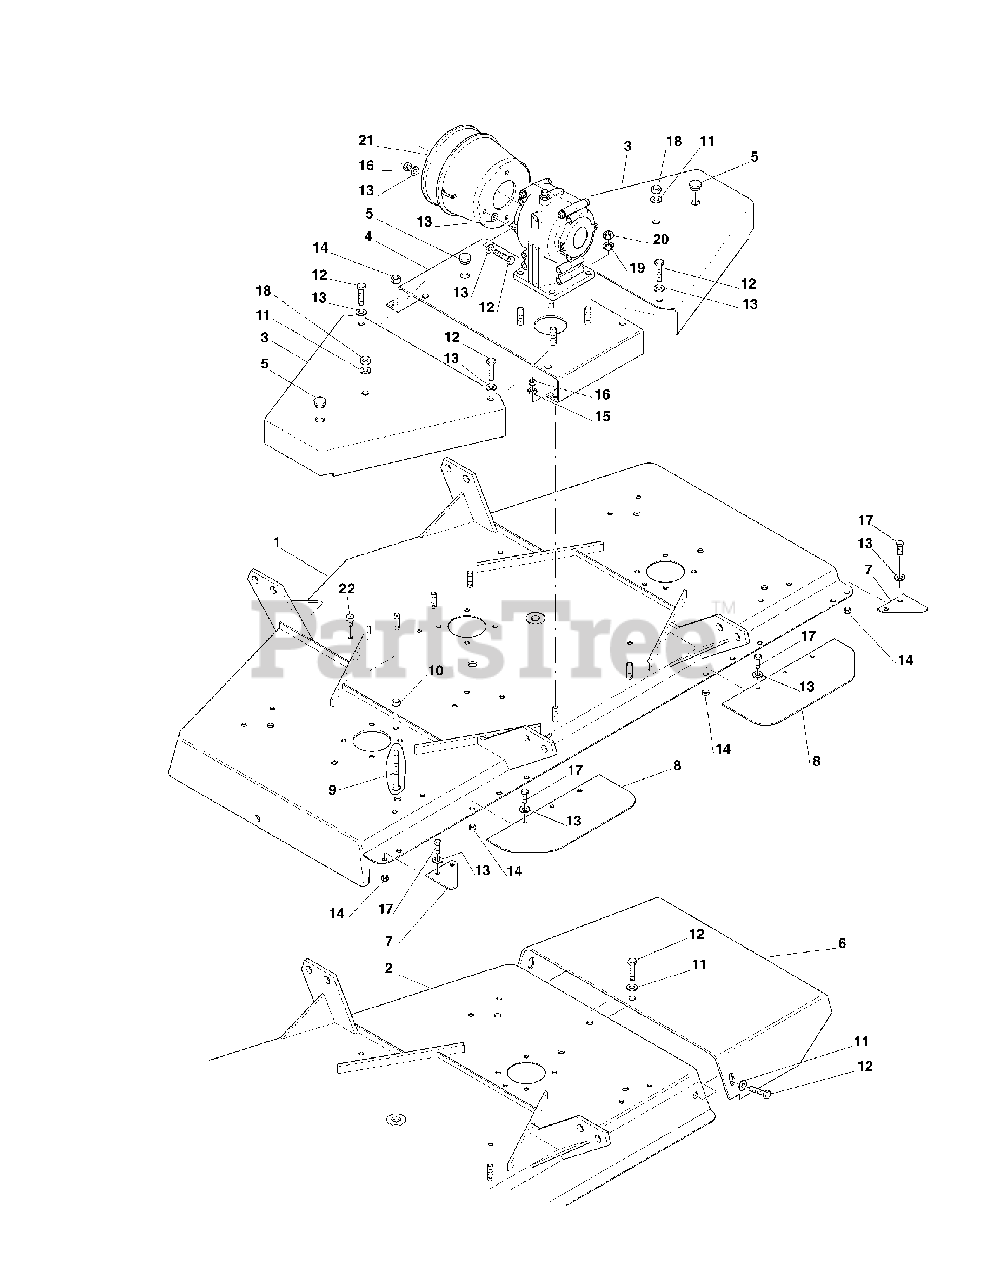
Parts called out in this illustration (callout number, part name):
1	Frame 48'' Rear Discharge
1	Frame 60'' Rear Discharge
1	Frame 72'' Rear Discharge
3	Belt Shield 48''
3	Belt Shield 60''
3	Belt Shield 72''
4	Central Plate 48''
4	Central Plate 60''
4	Central Plate 72''
5	Cap
6	Deflector 60''
7	Side Rear Protection 60''
7	Side Rear Protection 72''
8	Central Rear Protection
9	Bolt TE 10 x 110
10	Nut D. 10
11	Flat Washer D. 10
12	Bolt TE 10 x 110
13	Flat Washer D. 10
14	Nut D. 10
15	Spring Washer D. 10
16	Nut D. 10
17	Bolt TE 10 x 110
18	Nut D. 10
19	Spring Washer D. 12
20	Nut D. 12
21	Shaft Protection
